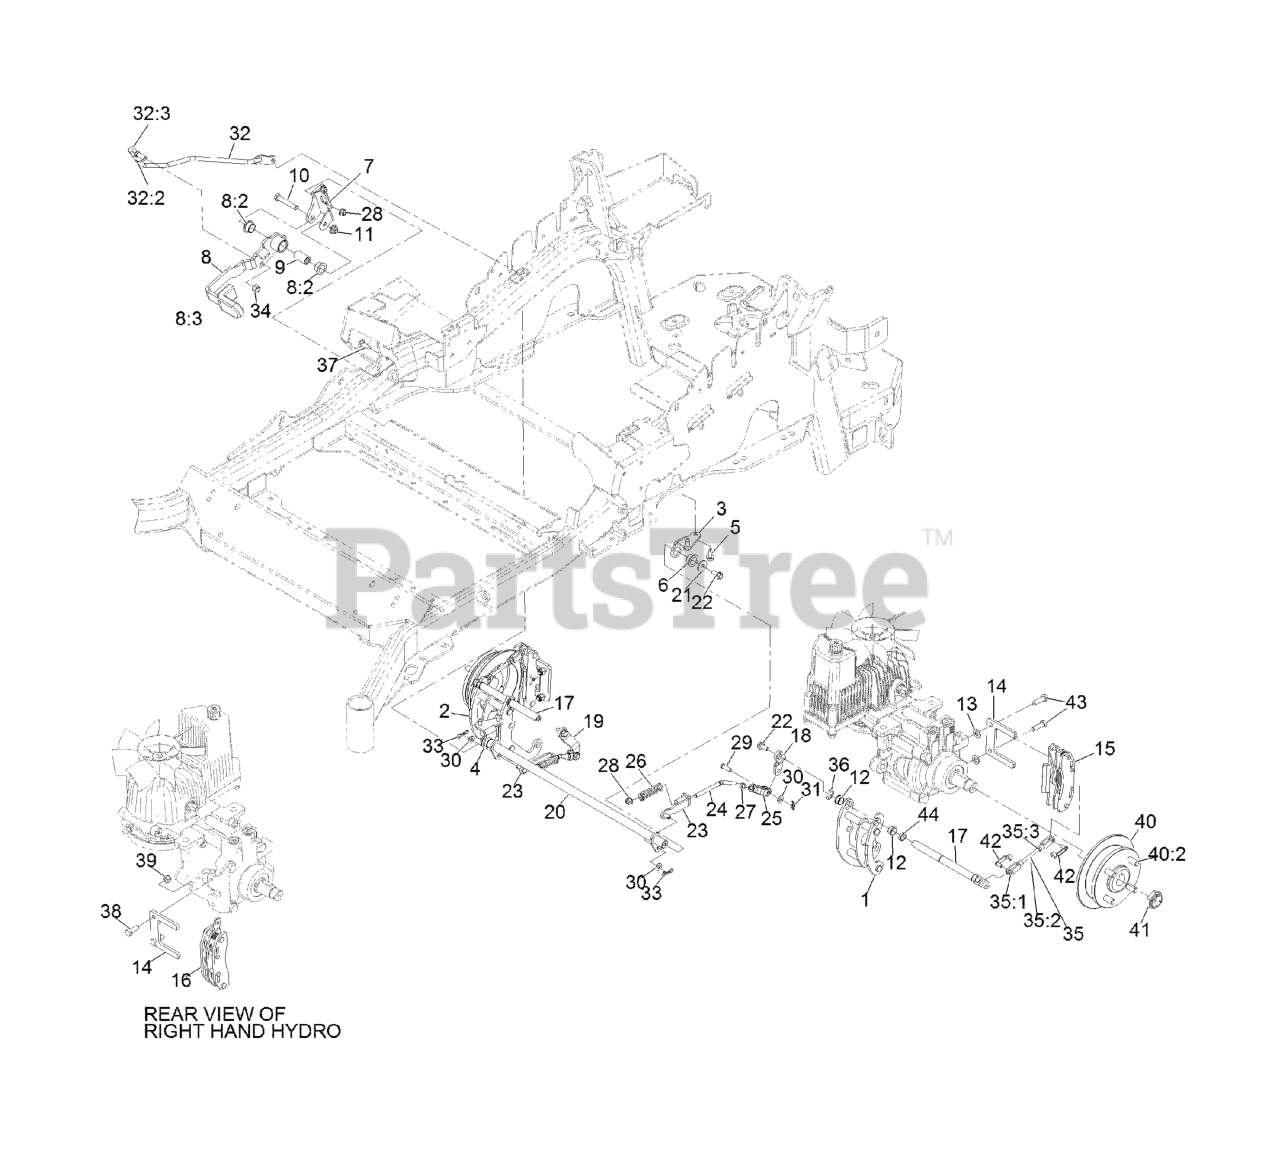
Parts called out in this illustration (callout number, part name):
1	MOUNT-BELLCRANK, LH
2	MOUNT-BELLCRANK, RH
3	MOUNT-PIVOT, LH
4	MOUNT-PIVOT, RH
5	Screw-HWH 5/16-18 X 3/4 Tf
6	BUSHING-FLANGE
7	BRACKET-MOUNT
8	BRAKE LEVER ASM W/ GRIP
8:2	BUSHING-FLANGE
8:3	GRIP-LEVER
9	HANDLE-PIVOT, BRAKE
10	SCREW-HH
11	NUT-HF, NI
12	BUSHING
13	WASHER-FLAT
14	PLATE-MOUNT, BRAKE
15	CALIPER-BRAKE
16	CALIPER-BRAKE, RH
17	BELLCRANK
18	ARM-INNER, LH
19	ARM-INNER, RH
20	SHAFT-CROSS
21	WASHER-FLAT
22	SCREW-HHF
23	BRACKET-L
24	LINKAGE-MID
25	YOKE-OFFSET
26	SPRING-COMPRESSION
27	NUT-JAM
28	NUT-HF, NI
29	PIN-CLEVIS
30	WASHER-PLAIN
31	PIN-COTTER, LOCKING
32	FRONT LINKAGE ASM
32:2	END-TIE ROD, RH
32:3	NUT-HJ
33	PIN-COTTER, LOCKING
34	NUT-LOCK
35	REAR LINKAGE ASM
35:3	NUT-JAM
37	BOLT-CARR
38	SCREW-HH
39	NUT-LOCK, NI
40	WHEEL HUB ASM
40:2	STUD-WHEEL
41	LOCKNUT
42	PIN-CLEVIS, SPRING
43	SCREW-LOCK, PATCH
